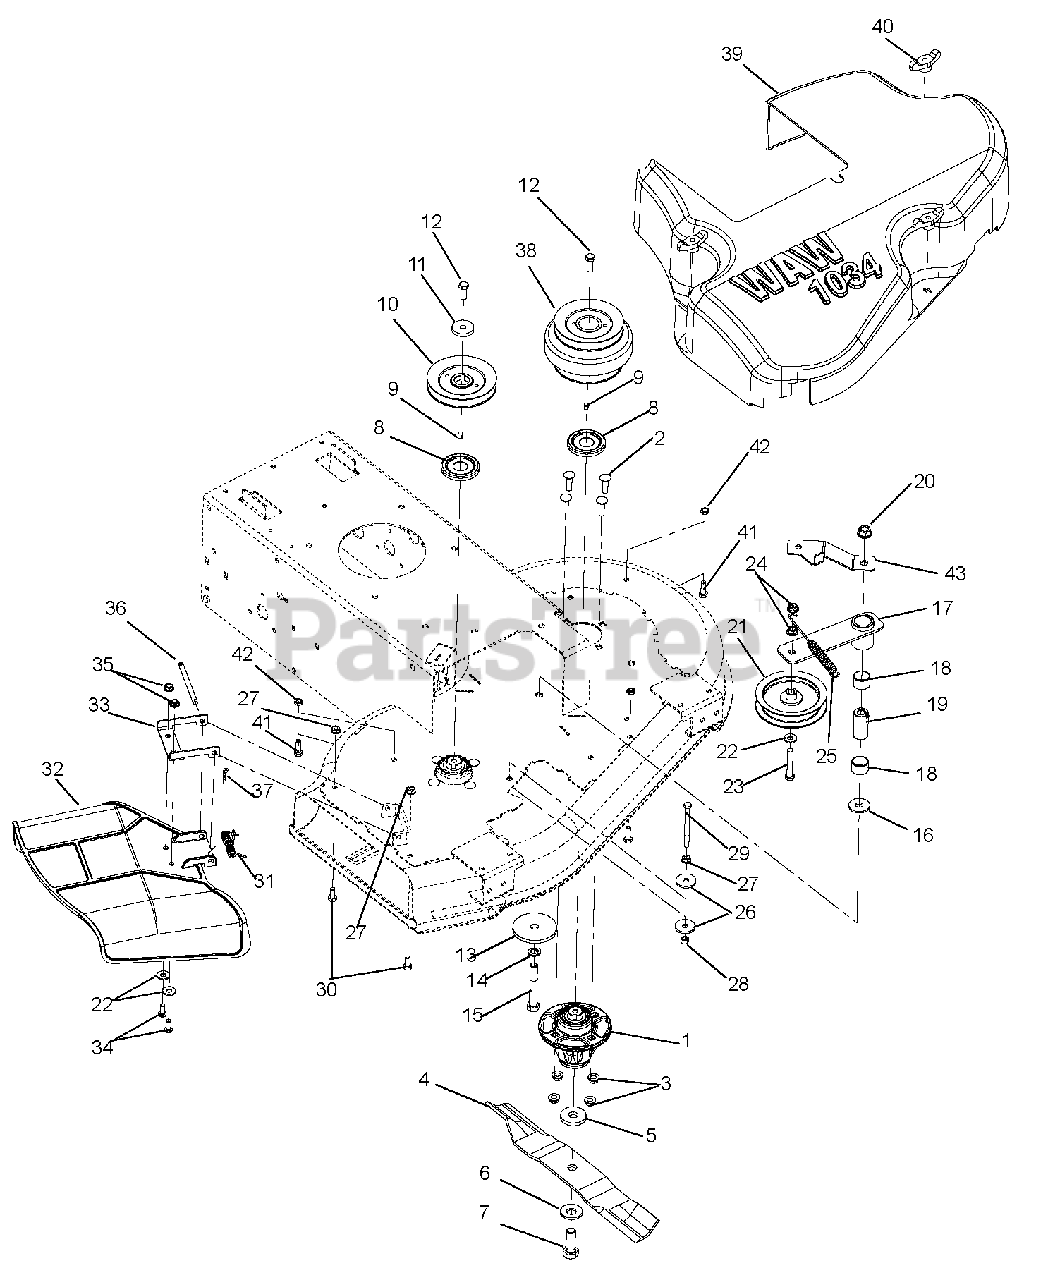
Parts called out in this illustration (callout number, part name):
1	Spindle Assembly
2	Bolt, Roundhead, Squareneck .38-16 x 1.25
3	Nut .38-16 Nyloc Flange
4	Blade 17.5 x 2.25 x .197
5	Washer, Flat .640 x 1.75 x .250
6	Washer, Bellville .63 x 1.62 x .14
7	Bolt, Hex .62-18 x 1.75 Grade 8
8	Cap, Dust
9	Key, Square .25 x .38 x
10	Sheave 4.75 Diameter A-Section
11	Washer, Flat Steel .406 x 1.50 x .245
12	Bolt, Hex .38-16 x 1.00
13	Washer, Flat .531 x 3.00 x .25
14	Washer, Locking .50 x .125
15	Bolt, Hex .50-13 x 3.50
16	Washer, Flat Steel .511 x 1.44 x .125
17	Arm, WAW Deck Idler
18	Bearing 1.00 x 1.12 x .75
19	Bushing, Spacer .505/.500 x .999/.996 x 2.05/2.03
20	Nut, Locking Top Flange .50-13
21	Idler Assembly, 4"
22	Washer, Flat Steel .38 x .875 x .083
23	Bolt, Hex .38-16 x 2.25
24	Nut, Locking Flange .375-16
25	Spring, Engine-Transmission
26	Washer, Flat Steel .406 x 1.375 x .135
27	Nut, Spin Lock-Flange .312-18
28	Nut, Locking Center .31-18
29	Bolt, Hex .31-18 x 3.50
30	Bolt, Hex .31-18 x .75
31	Spring, Torsion
32	Chute, Molded
33	Reinforcement, Chute
34	Screw, Socket Head .31-18 x .75 Button Head
35	Nut, Locking Top Flange .31-18
36	Pin, .3125 x 3.88
37	Pin, Internal Hair .08 x .18 x 1.18
38	Pulley, Deck Input
39	Cover, Belt
40	Knob, Wing .312-18
41	Bolt, Hex .31-18 x 1.00
42	Nut, Locking Center .31-18
43	Bracket, Idler Brace
